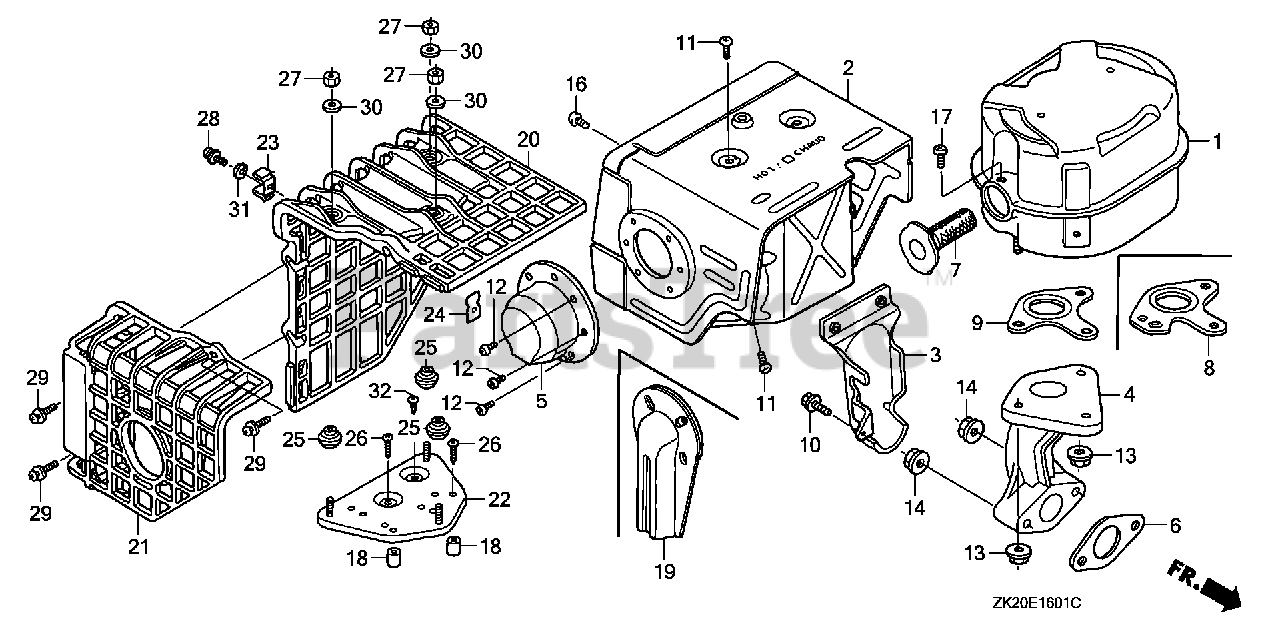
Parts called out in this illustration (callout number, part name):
1	MUFFLER
2	PROTECTOR, MUFFLER (STD)
3	PROTECTOR, EX. PIPE
5	CAP, MUFFLER
6	GASKET, EX. PIPE
7	ARRESTER, SPARK
8	GASKET, MUFFLER (ARRESTER) (NIPPON LEAKLESS)
9	GASKET, MUFFLER (NIPPON LEAKLESS)
10	BOLT, FLANGE (6X12) (CT200)
11	SCREW, TAPPING (5X8)
12	SCREW, TAPPING (4X6)
13	NUT, FLANGE (8MM)
14	NUT, FLANGE (8MM)
16	SCREW, TAPPING (5X8)
17	SCREW, TAPPING (4X6)
